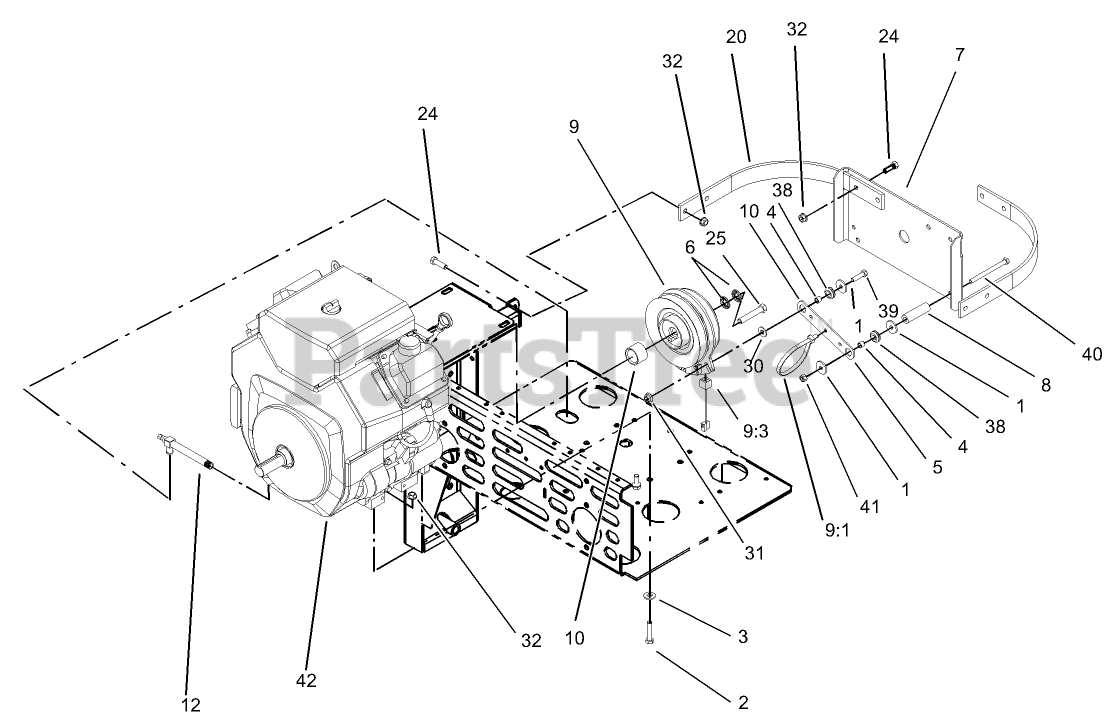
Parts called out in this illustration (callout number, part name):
1	WASHER
2	SCREW-HH
3	WASHER-BELLEVILLE
4	SPACER
5	STRAP-CLUTCH, BRAKE
6	WASHER-SPRING
7	GUARD-CLUTCH
8	SPACER-ANCHOR, CLUTCH
9	CLUTCH ASM
9:1	TIE-PLASTIC
9:3	HARNESS-JUMPER, CLUTCH
10	SPACER-CLUTCH
12	VALVE-OIL DRAIN, LONG
20	BRACKET-GUARD, TOP
24	SCREW-HH
25	SCREW-HH
30	WASHER-FLAT
31	NUT-HF
32	NUT-HHF, WHIZ
38	GROMMET
39	SCREW-HH
40	SCREW-HH
41	NUT-LOCK, NI
